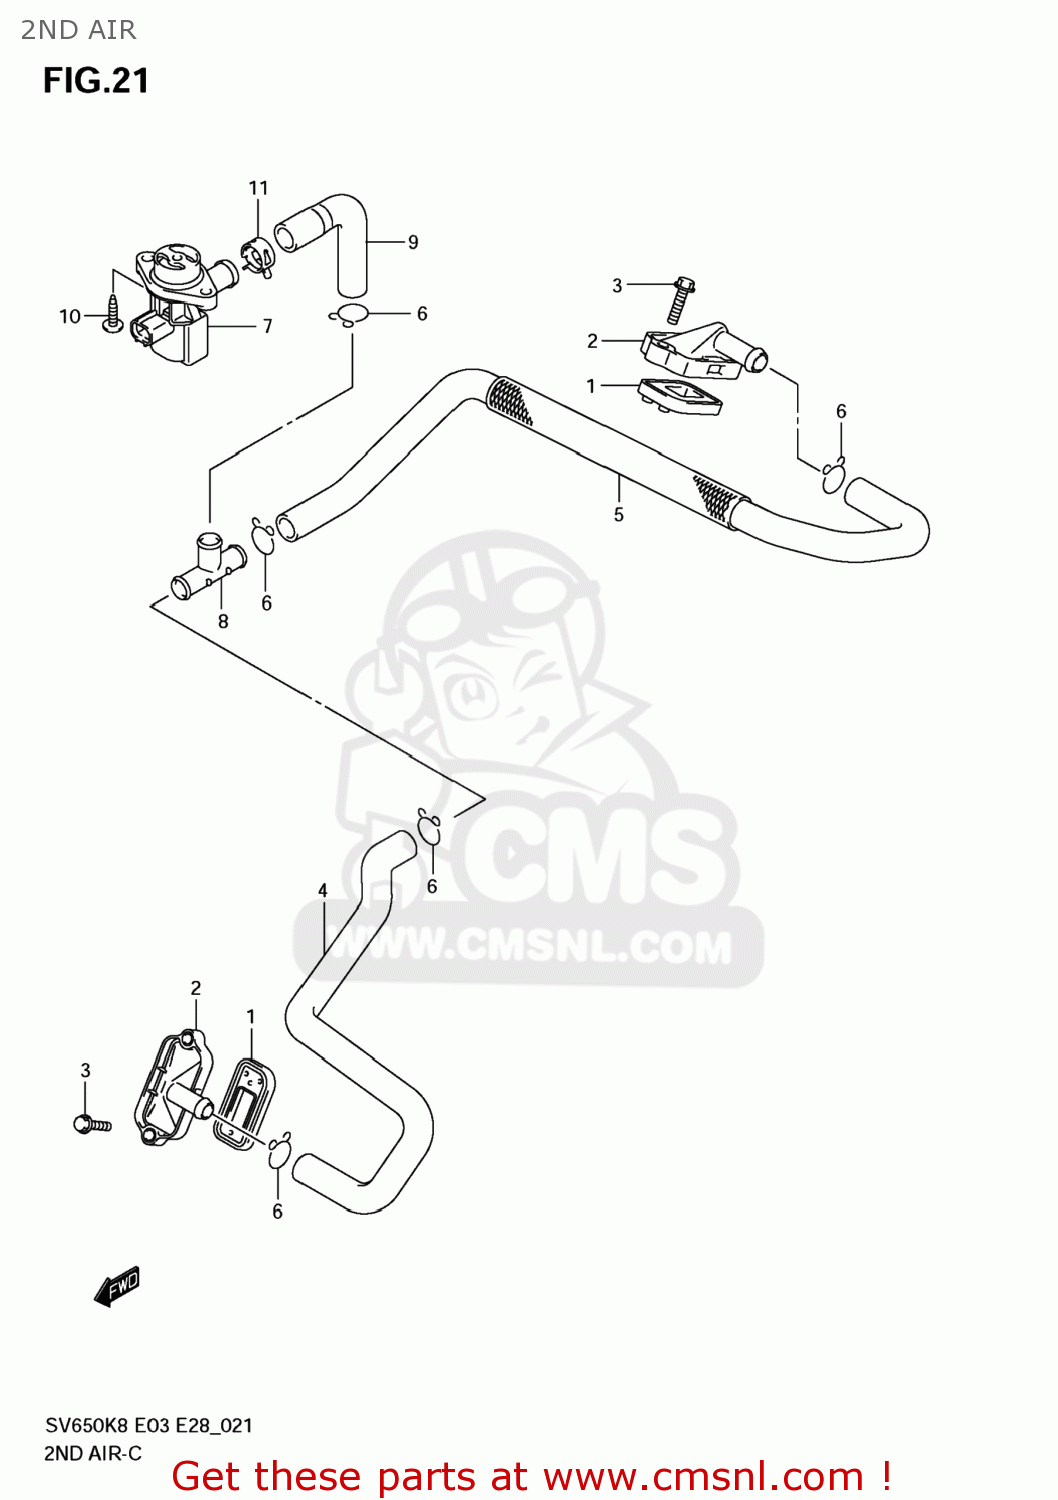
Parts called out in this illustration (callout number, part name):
1	VALVE ASSY,2ND AIR REED
2	COVER,2ND AIR
3	BOLT(6X20)
4	HOSE,2ND AIR VALVE FR
5	HOSE,2ND AIR VALVE RR
6	CLIP
7	VALVE ASSY,AIR CUT
8	JOINT
9	HOSE,2ND AIR VALVE
10	SCREW
11	CLAMP
